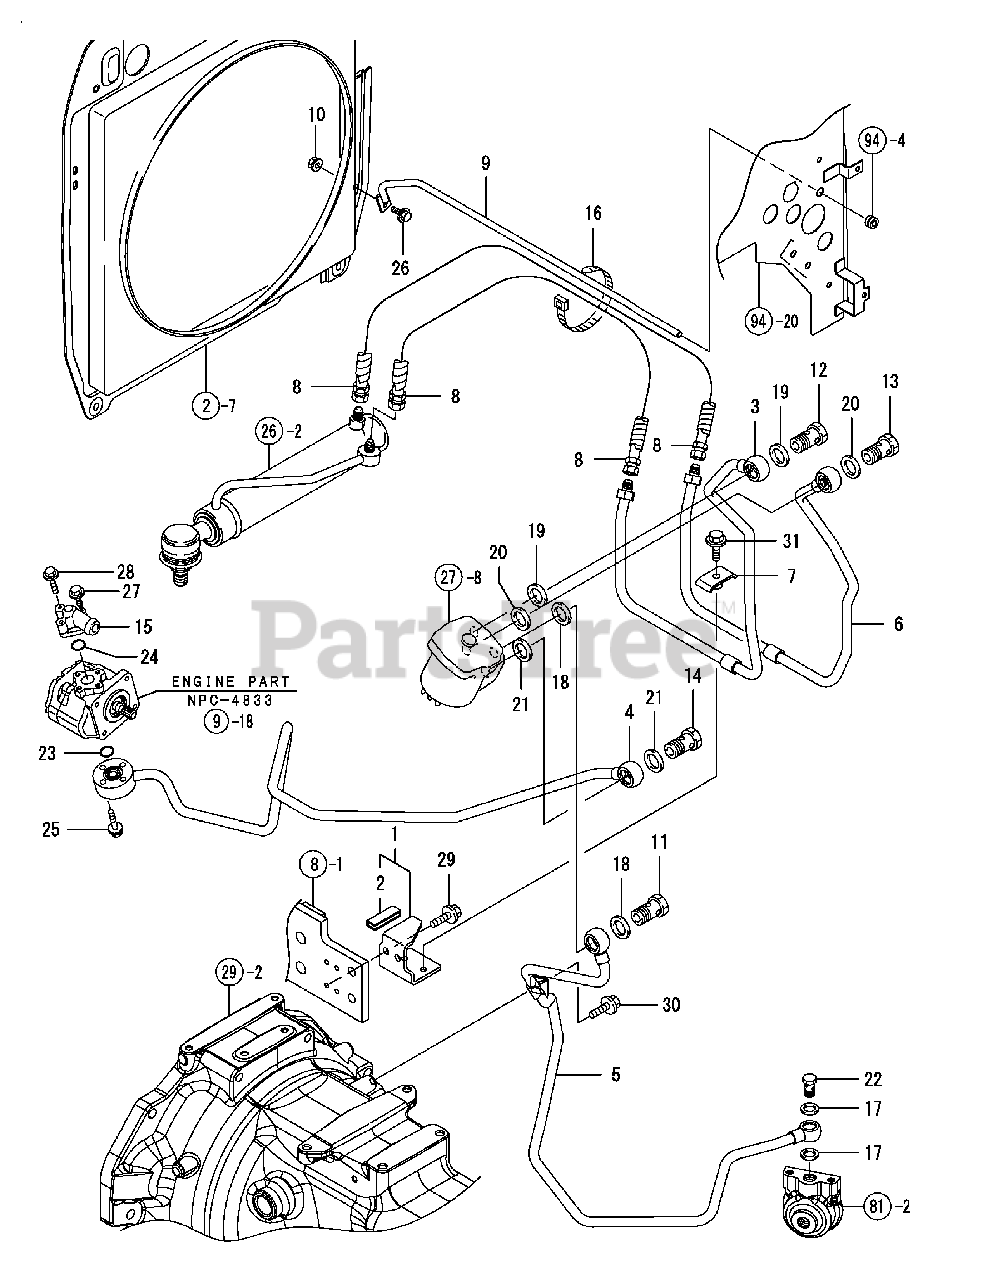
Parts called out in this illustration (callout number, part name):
7	CLAMP, PIPE 12
10	NUT W/WASHER 6
16	BAND 140,WIRE LOCK
23	O-RING 1A P-20.0
24	O-RING 1A P-20.0
26	BOLT M 6X 12 PLATED
27	BOLT M 6X 20 PLATED
28	BOLT M 6X 40 PLATED
29	BOLT M 8X 12 PLATED
30	BOLT M 8X 16 PLATED
31	BOLT M 8X 25 PLATED
